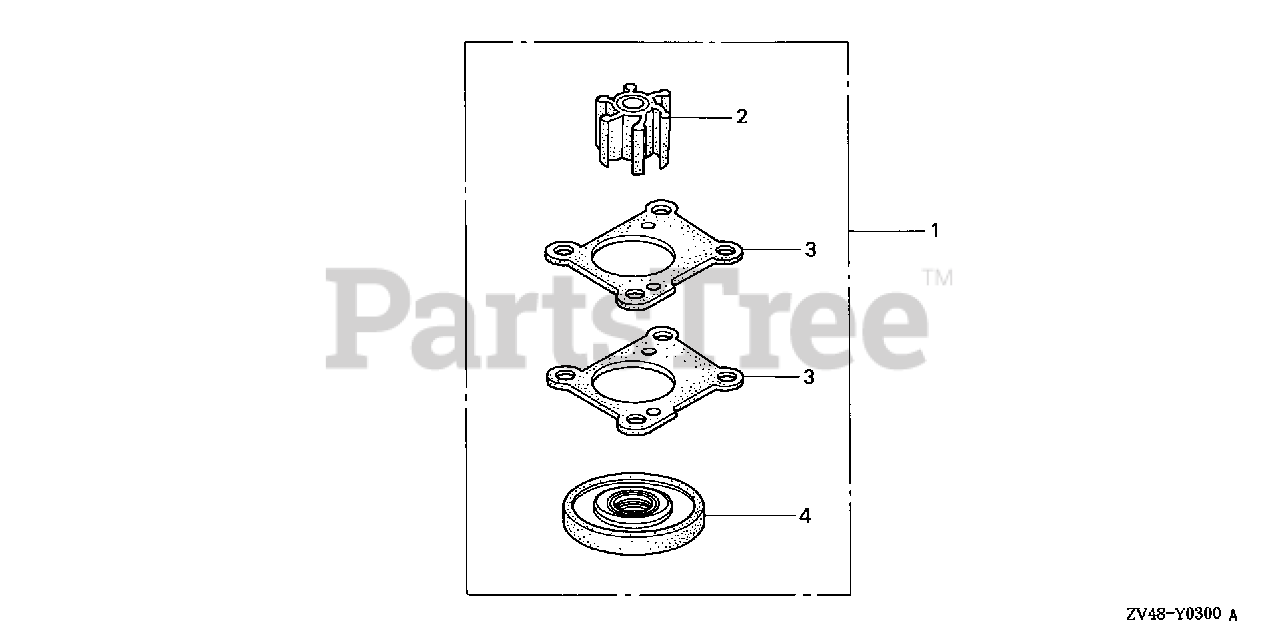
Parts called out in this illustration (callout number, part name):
1	IMPELLER KIT, WATER PUMP
1	PUMP KIT, IMPELLER
2	IMPELLER, PUMP
3	GASKET, IMPELLER
4	SEAL, WATER (15MM) (NOK)
